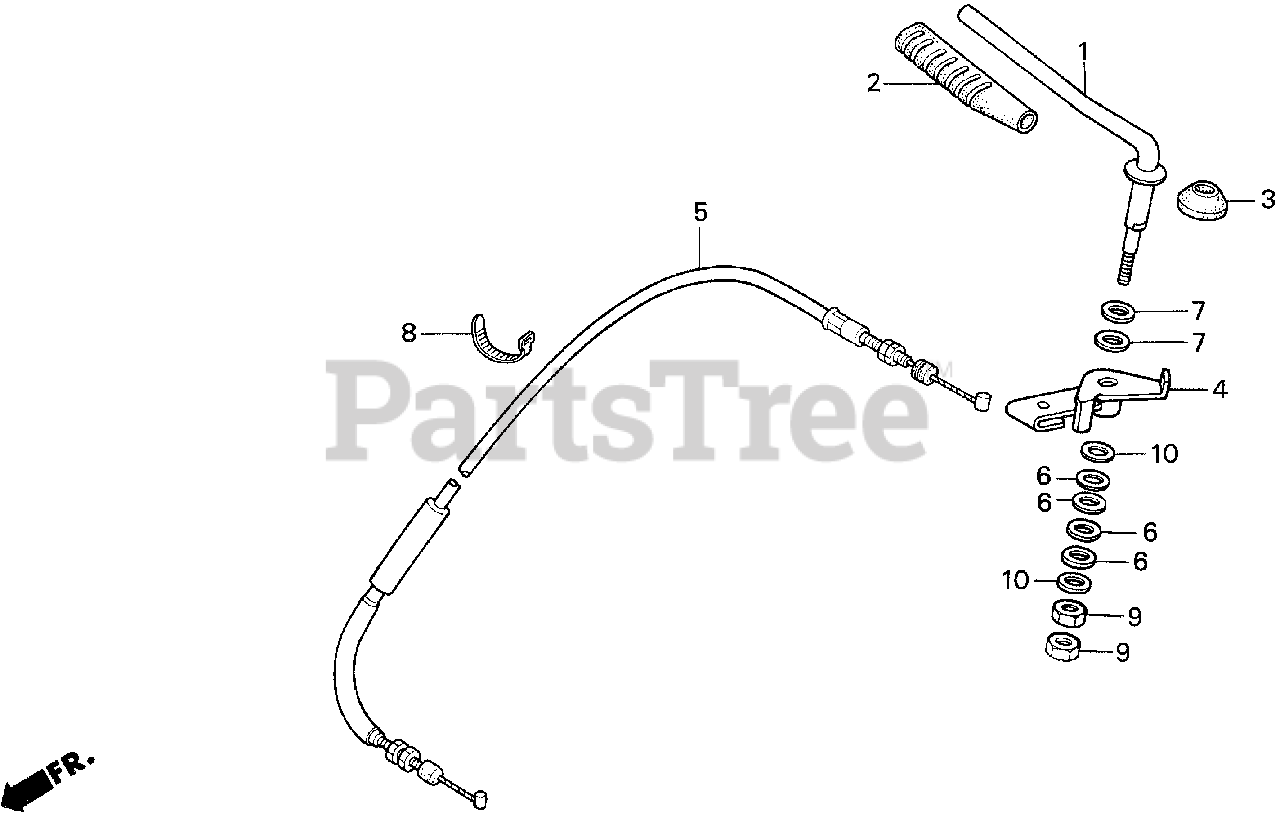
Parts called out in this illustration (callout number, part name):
1	LEVER, THROTTLE
2	GRIP, THROTTLE LEVER *YR161* (ORANGE)
3	COVER, THROTTLE LEVER
4	PLATE, THROTTLE CONTROL
5	CABLE, THROTTLE
6	WASHER, CONICAL SPRING
7	WASHER, THRUST (12MM)
8	BAND, CABLE (120MM) (BLACK)
9	NUT, HEX. (8MM)
10	WASHER, PLAIN (8MM)
